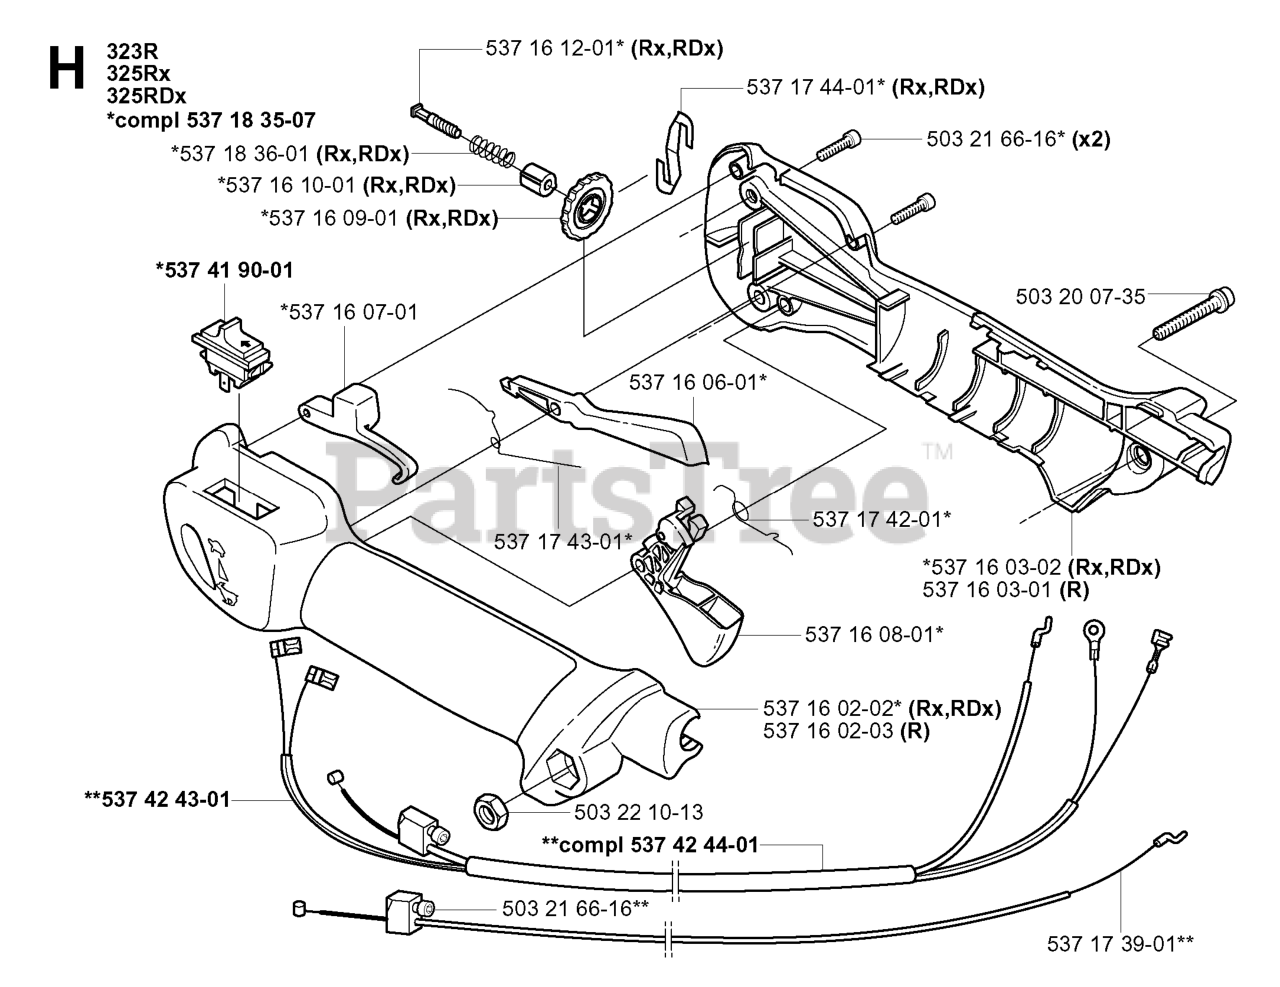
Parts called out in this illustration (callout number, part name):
1	GEAR BOX ASM CAST
2	IMPELLER CAST.IRON.12IN MS 417
3	PULLEY SCREW ON 7.9
4	SUPPORT.GEARBOX.LS.498
5	CHUTE.DISCHARGE.BASE
6	BRACKET, CORNER DISCHARGE
7	BOLT.1/4-20 X 1-13/16 SHEAR
8	LOCKNUT.NYLOC.1/4-20
9	BOLT.CARRIAGE.5/16-18
10	NUT HEX FLG NYLOCK BLK 5_16-1
11	BOLT CAR BLK 5/16-18 X 5/8
12	BOLT, HEX HEAD 5/16-18
13	BOLT CARR WAFER BLK 5_16-18 X
14	NUTNYLOK.FLRANGE.5/16-18
15	BEARING FLANGE
